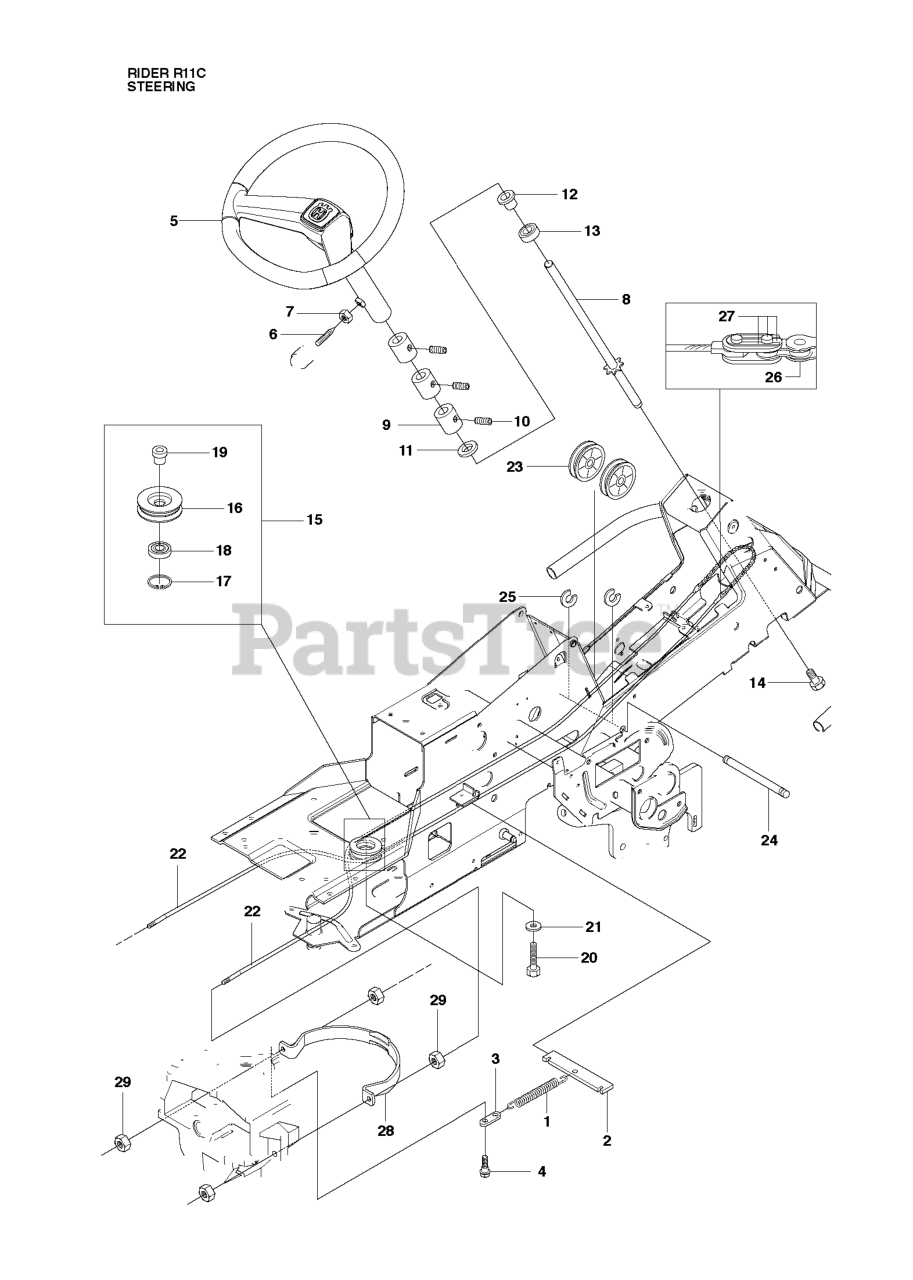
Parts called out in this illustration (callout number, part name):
2	SPRING BRACKET
5	STEERING WHEEL
7	NUT
8	STEERING ROD
9	SPACER
13	BALL BEARING 6004-2RS1
17	CIRCLIP SGH 47
18	BALL-BEARING 6204-2RS
22	RP STEERING CABLE COMPLETE
24	SHAFT
25	RETAINING RING
26	STEERING CHAIN
28	WIRE GUIDE
29	NUT
